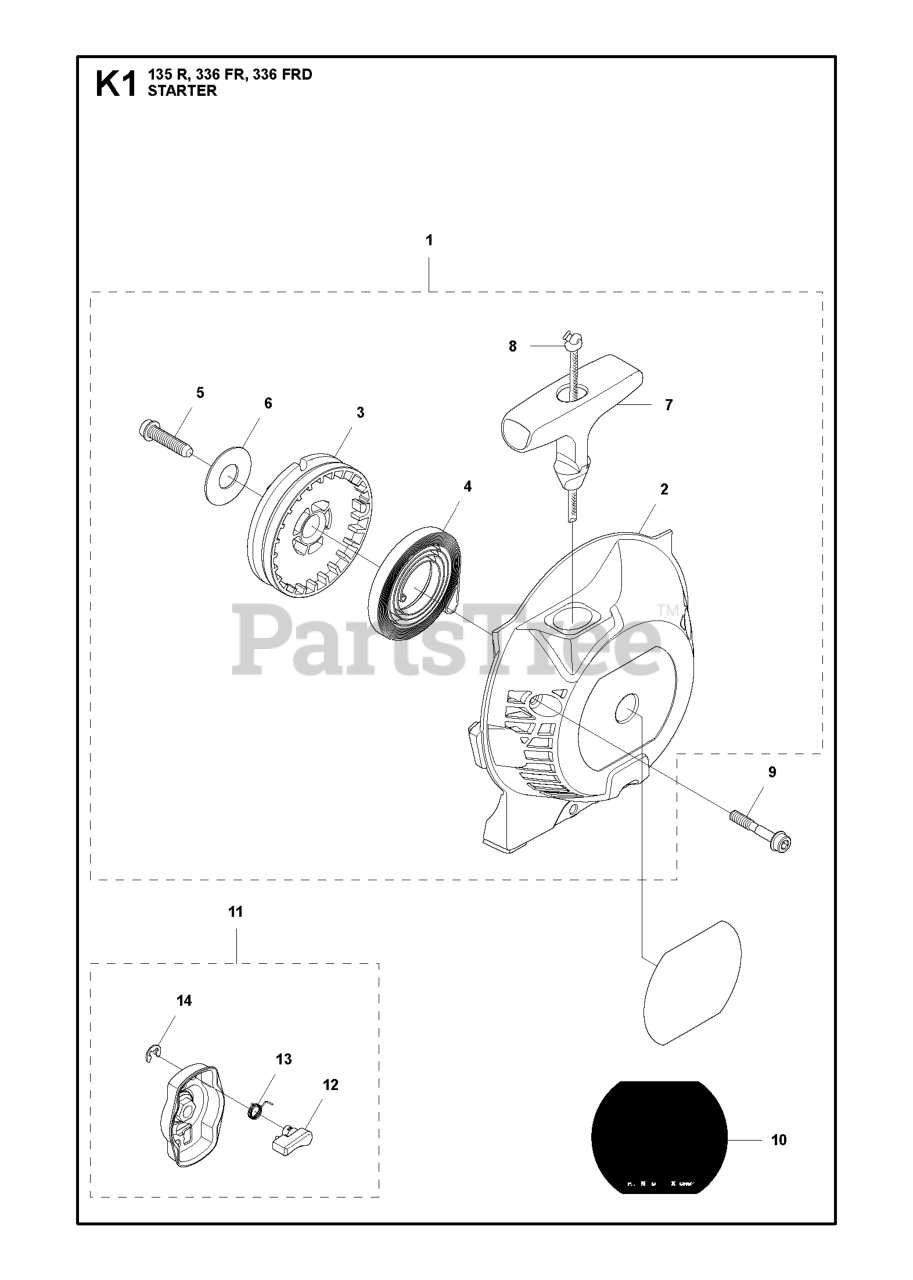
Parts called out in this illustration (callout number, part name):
1	STARTER ASSY
2	STARTER HOUSING
3	STARTER PULLEY
4	STARTER SPRING
8	STARTER ROPE
9	SCREW IHSCFMO
11	STARTER PAWL BRIDGE
12	STARTER PAWL
